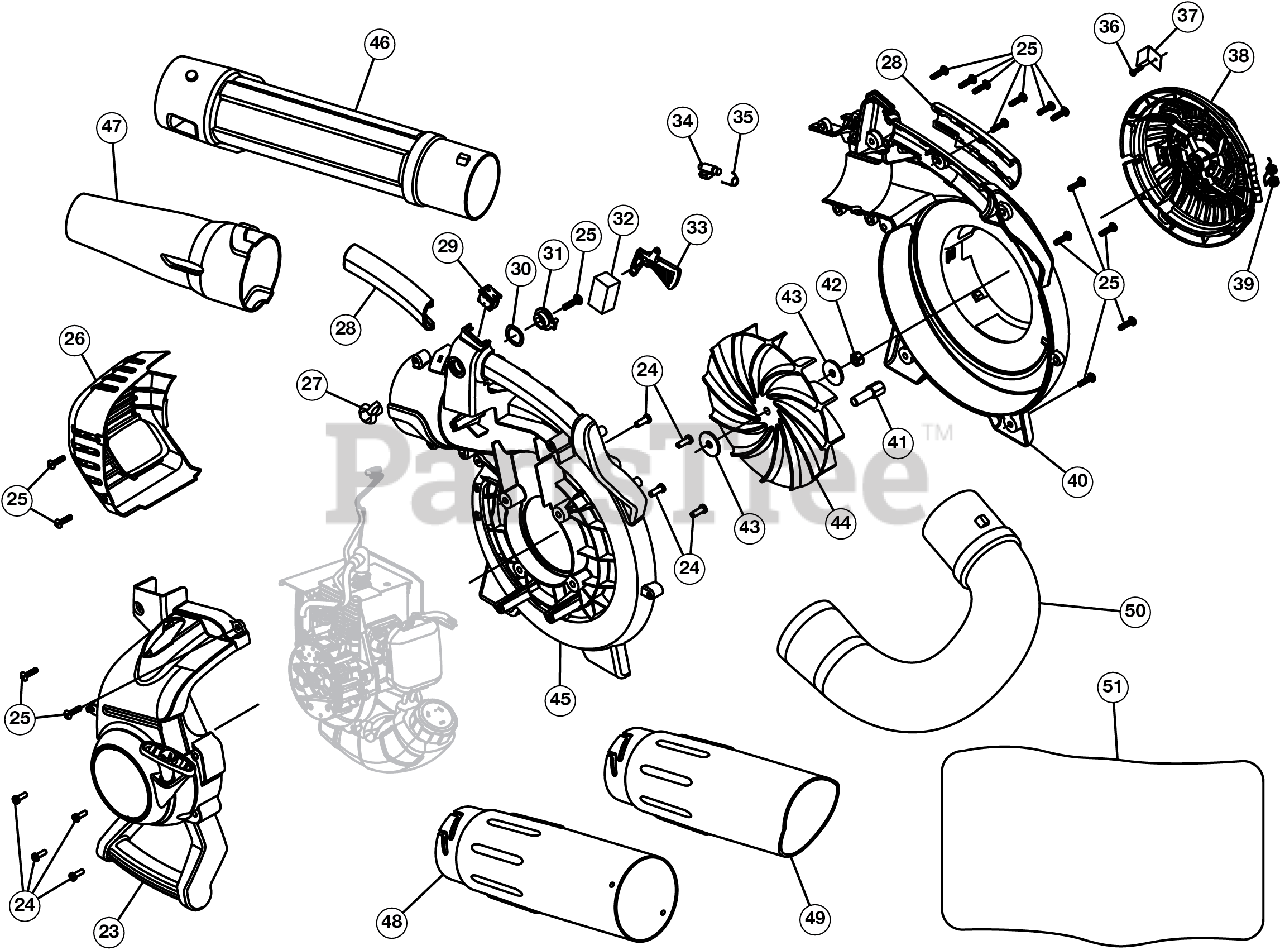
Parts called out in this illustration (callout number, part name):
23	STARTER HOUSING ASSEMBLY
24	SCREW:10-32X.562:#8P
25	SCREW 8-16 x 3/4
26	MUFFLER COVER
27	TRIGGER LOCK OTR
28	ANDLE GRIP ASSEMBLY
29	SW, MOMENTARY ON/O
30	WASHER WAVEY
31	TRIGGER LOCK INR
32	AIR FILTER
33	THROTTLE TRIGGER
34	LATCH TUBE
35	SPRING LATCH
36	SCREW-10-9 x .50
37	DOOR LOCK SC
38	INTAKE COVER BLK
39	SPRING
40	IMPELLER HOUSING OTR
41	ADAPTER STARTER
42	HEX NUT CENTER
43	WASHER FLAT
44	IMPELLER
45	IMPELLER HOUSING INR
46	UPPER TUBE
47	NOZZLE BKPK CUB
48	UPPER VAC TUBE SCBLO
49	TUBE, LOWER VACUUM (ELEC BLWR-
50	ELBOW TUBE
51	VAC BAG SCBLO
